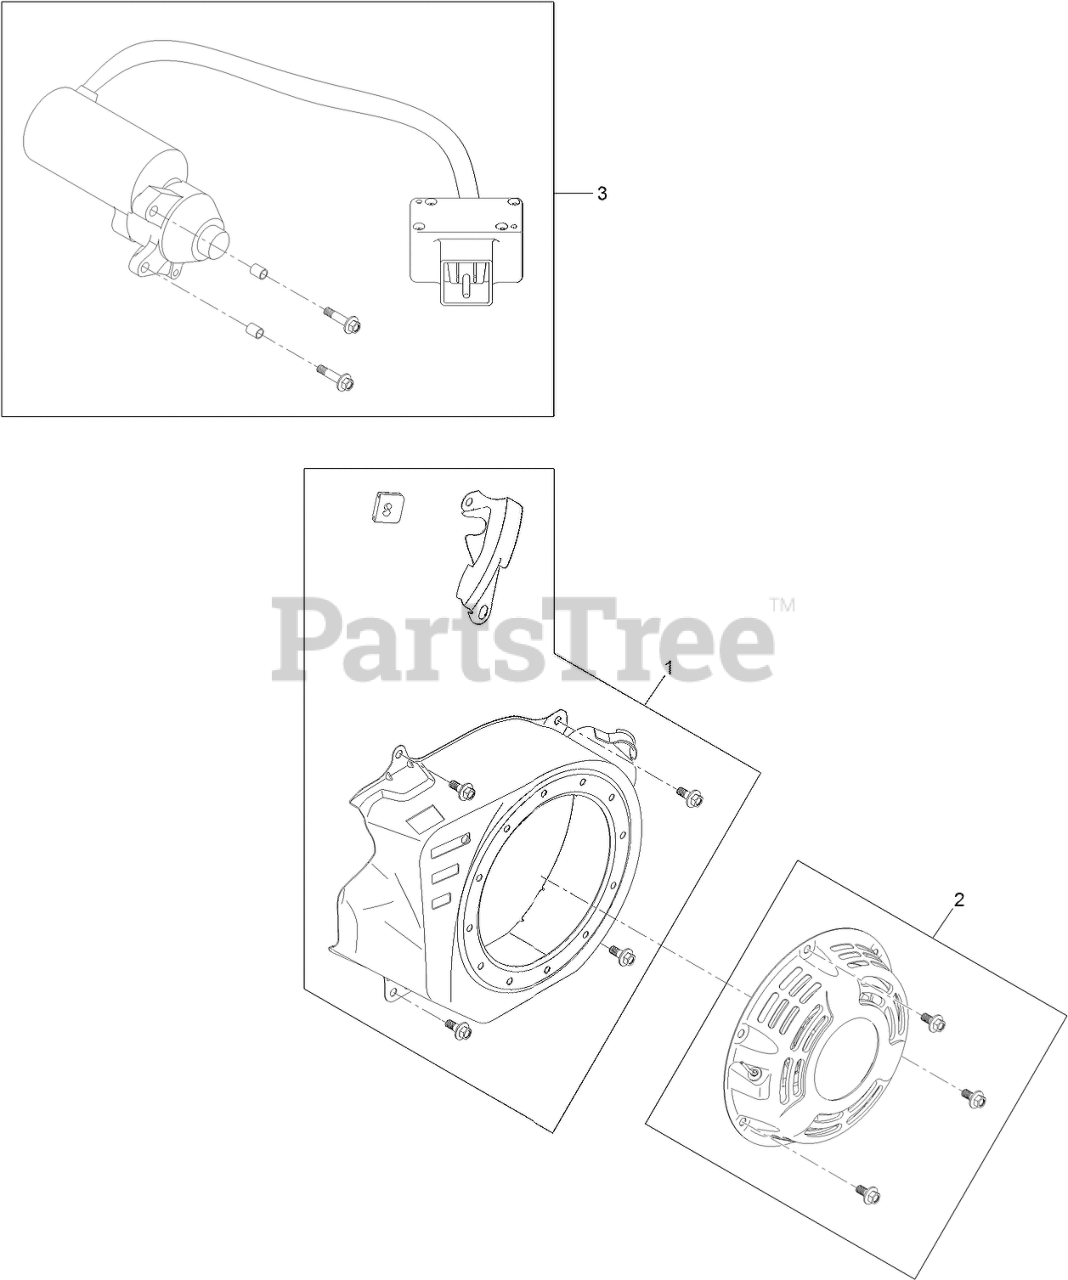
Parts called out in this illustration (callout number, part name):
1	BLOWER SHROUD KIT
2	RECOIL KIT
3	ELECTRIC STARTER KIT
